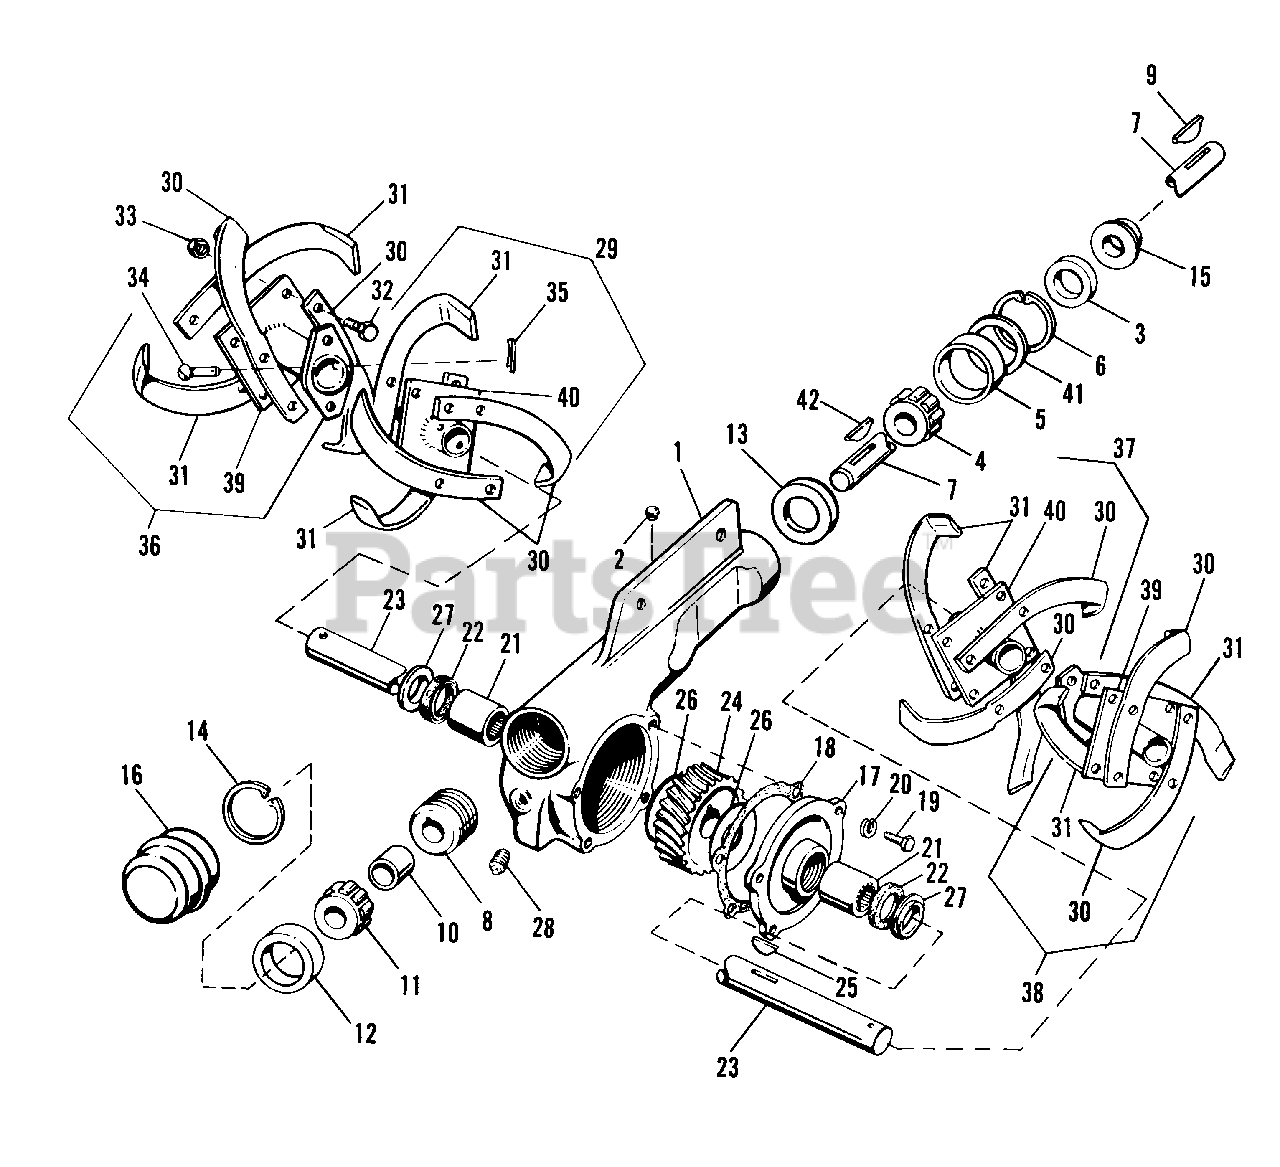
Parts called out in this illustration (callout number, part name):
1	WORM DRIVE HOUSING
4	BEARING, Roller
5	BEARING, Cup
6	RING, Snap
7	SHAFT, Worm
8	WORM, R.H.
11	BEARING, Roller
12	BEARING, Cup
14	RING, Snap
16	CUP
19	CAPSCREW, Hex, 1/4-20 x 5/8
20	LOCKWASHER, 1/4
21	BEARING, Needle
23	SHAFT, Worm Gear
24	WORM GEAR, R.H.
25	KEY, Woodruff #91, 1-1/4 x 3/4
26	WASHER, Thrust
28	PLUG, Pipe
29	TINE ASSY, R.H. Inner
30	TINE BLADE, L.H.
31	TINE BLADE, R.H.
32	CAPSCREW, Hex, 7/16-20 x 1-1/4
33	LOCKNUT, Hex, Full, 7/16-20
34	PIN
35	PIN, Cotter, 1/8 x 3/4
36	TINE ASSY, Outer, R.H.
37	TINE ASSY, Inner, L.H.
38	TINE ASSY, Outer, L.H.
39	PLATE ASSY, Outer
40	PLATE ASSY, Inner
41	RING, Backing
42	KEY
